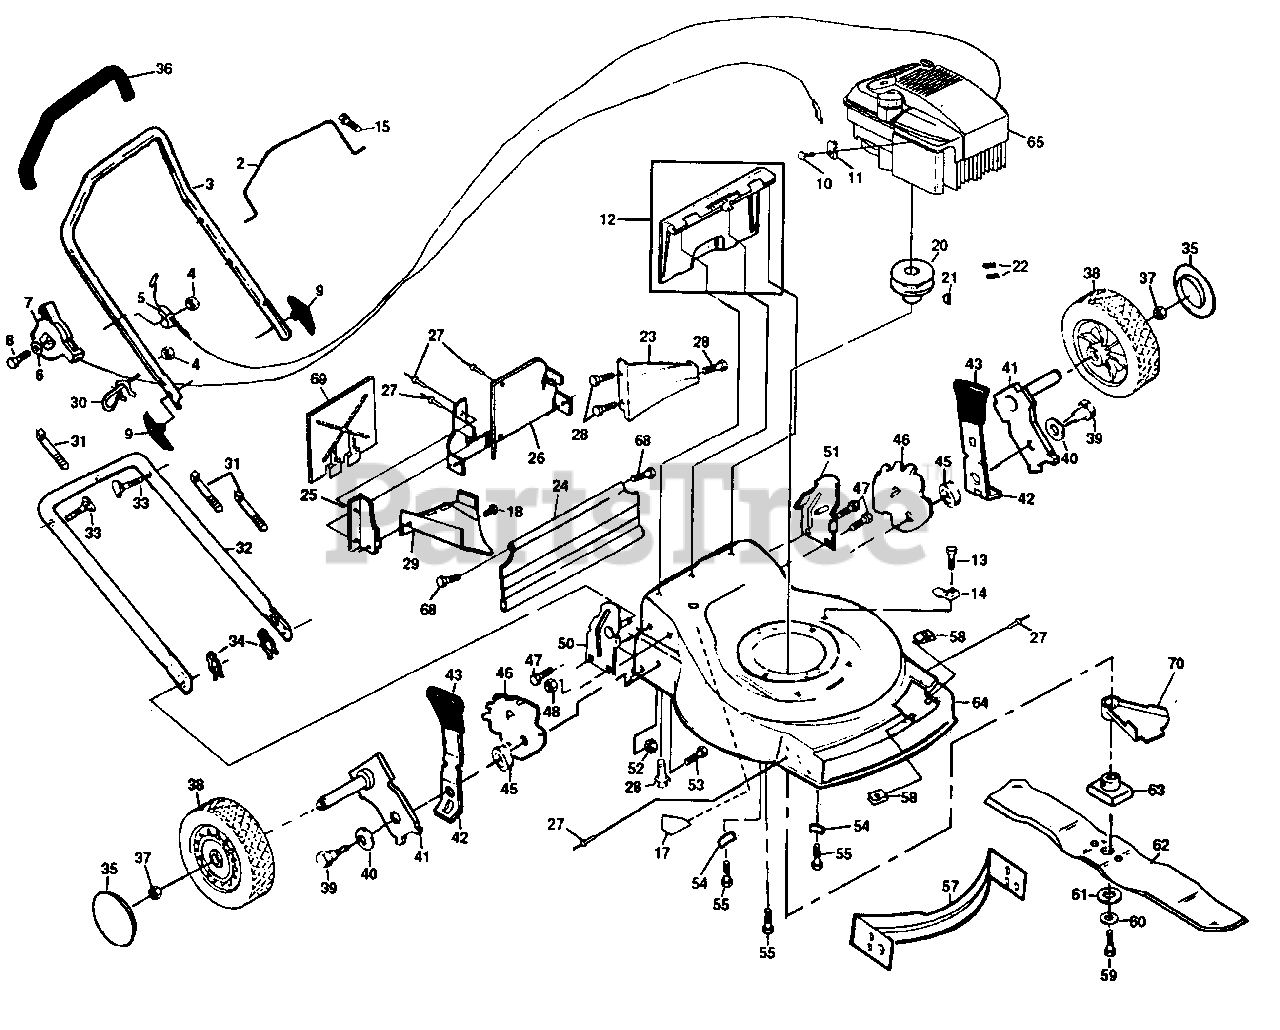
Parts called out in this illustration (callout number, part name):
2	Control Bar (AYP part number)
3	Upper Handle (AYP part number)
4	Locknut (AYP part number)
5	Engine Zone Control Cable
6	Washer (AYP part number)
7	Throttle Control (AYP part number)
8	Machine Screw 1/4-20 x 2-1/8 (AYP part number)
9	Handle Knob (AYP part number)
10	Screw #10 x 5/8 (AYP part number)
11	Cable Clamp (Engine) (AYP part number)
12	Rear Door Kit (AYP part number)
13	Hex Washer Head Screw #10-24 x 1/2 (AYP part number)
14	Housing Cable Guide (AYP part number)
15	Self-tapping Screw #10-24 x .625 (AYP part number)
17	Danger Decal (AYP part number)
18	Screw (AYP part number)
20	Engine Pulley (AYP part number)
21	Hi Pro Key #505 (AYP part number)
22	Set Screw 1/4-20 x 5/16 (AYP part number)
23	Baffle, Rear (AYP part number)
24	Rear Skirt (AYP part number)
25	Side Baffle (AYP part number)
26	Back Plate (AYP part number)
27	Pop Rivet (AYP part number)
28	Screw Hex Head 1/4-20 x 1/2 (AYP part number)
29	Discharge Baffle (AYP part number)
30	Rope Guide
31	Wire Tie (AYP part number)
32	Lower Handle (AYP part number)
33	Handle Bolt (AYP part number)
34	Hairpin Cotter (AYP part number)
35	Hubcap (AYP part number)
36	Grip, Handle, Foam, Corduroy (AYP part number)
37	Hex Flange Locknut 3/8-16 (AYP part number)
38	Wheel & Tire Assembly 9.00 x 2.00
39	Shoulder Bolt (AYP part number)
40	Belleville Washer (AYP part number)
41	Axle Arm (AYP part number)
42	Selector Spring (AYP part number)
43	Selector Knob
45	Spacer (AYP part number)
46	Wheel Adjusting Bracket (AYP part number)
47	Self-tapping Screw 5/16-18 x 3/4 (AYP part number)
48	Locknut 5/16-18 (AYP part number)
50	Handle Bracket (Right) (AYP part number)
51	Handle Bracket (Left) (AYP part number)
52	Locknut 3/8-16 (AYP part number)
53	Carriage Bolt 5/16-18 x 5/8
54	Engine Washer (AYP part number)
55	Hex Head Thread Rolling Screw 3/8-16 x 1 (AYP part number)
57	Front Baffle (AYP part number)
58	Speed Nut (U Type) (AYP part number)
59	Hex Head Machine Screw 3/8-24 x 1-3/8 Gr. 8
60	Helical Lock Washer (AYP part number)
61	Hardened Washer (AYP part number)
62	Blade 22" (AYP part number)
63	Blade Adapter
64	Lawn Mower Housing Kit (Inc.17)
68	Screw, Hinge (AYP part number)
69	Plate, Mulcher (AYP part number)
70	Shield, Debris (AYP part number)
